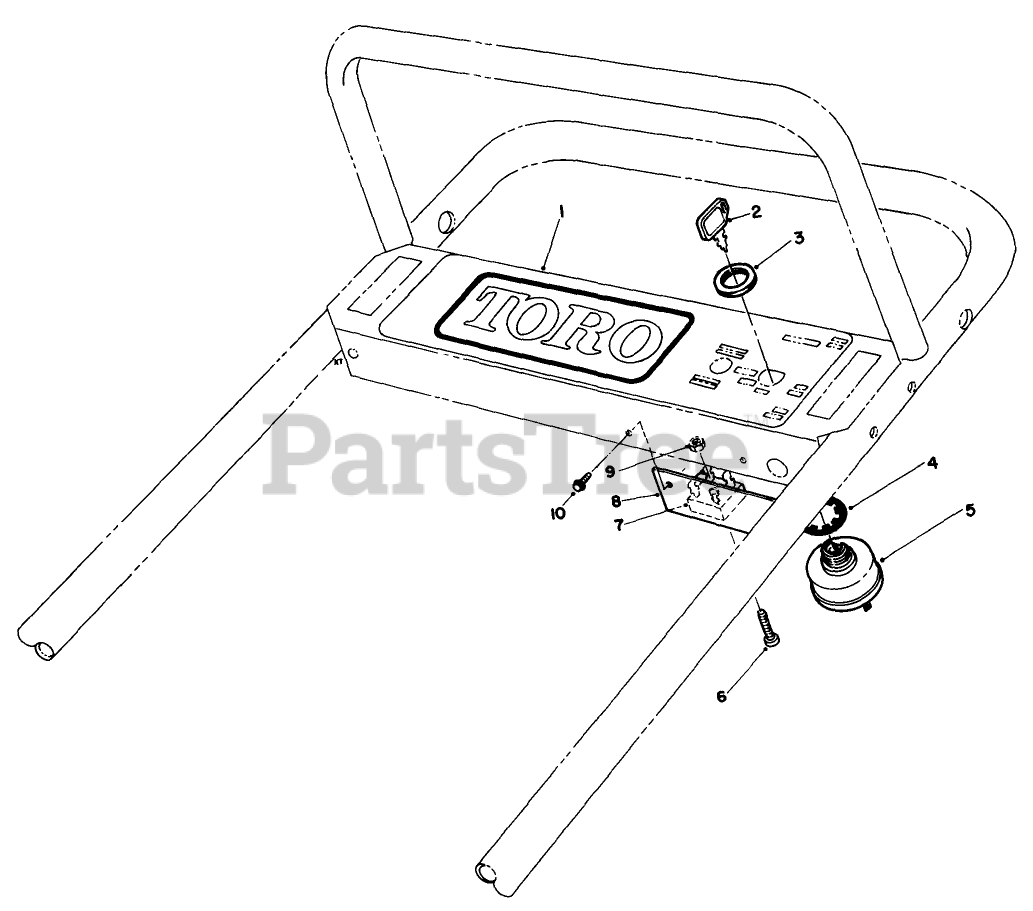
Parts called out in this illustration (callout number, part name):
2	KEY-IGNITION
3	NUT-HH
4	WASHER-LOCK
5	SWITCH-STARTER
6	SCREW-HWH
7	RECTIFIER-BRIDGE
8	BOTTOM PANEL *B
9	NUT-LOCK, NI
10	SCREW-HWHTF
